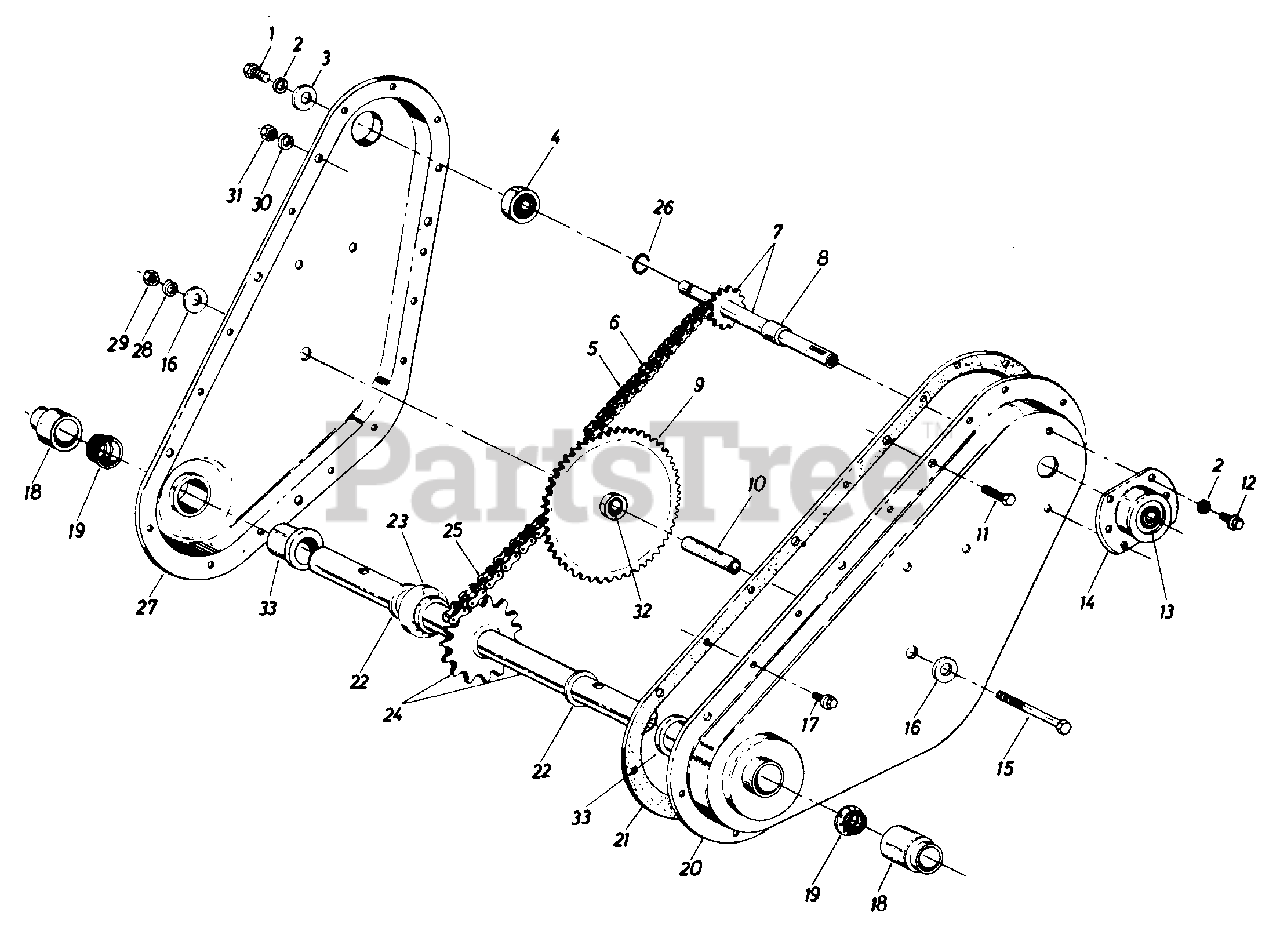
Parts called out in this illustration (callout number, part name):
1	Hex L-Scr. 1/4-28 x .625" Lg.
2	L-Wash. 1/4" I.D.
3	Fl-Wash. .25" I.D. x .93" O.D. x .125" Thk.
4	Bearing .62" I.D. x 1.38" O.D. x .437n Thk.
5	#35 Chain 3/8" Pitch x 52 Links Endless
6	Master Link
7	Input Shaft Assembly
8	Spacer
9	Sprocket Assembly
10	Sprocket Hub Tubing 3/8" I.D. x 5/8" O.D. x 1.9" Lg.
11	Hex Scr. 5/16-18 x .625" Lg.
12	Hex Wash. Hd. Self-Tap Scr. 1/4-20 x .50" Lg.
13	Bearing .625" I.D. x 1.38n O.D. x .437" Thk.
14	Bearing Housing
15	Hex Scr. 3/8-24 x 2 75" Lg.
16	Fl-Wash. 3/8" I.D. x 1.25" O.D. x .100 Thk.
17	Hex Wash. Hd. Self-Tap Scr. 1/4-20 x .50" Lg.
18	Dust Cap
22	Thrust Wash. 1.00" I.D. x 030n Thk.
23	Step Spacer
24	Tine Shaft Assembly
25	#50 Chain 5/8n Pitch x 46 Links Endless
26	Snap Ring
29	Hex Nut 3/8-24 Thd.
30	L-Wash. 5/16" Scr.
31	Hex Nut 5/16-18 Thd.
32	Bearing
33	Bearing
